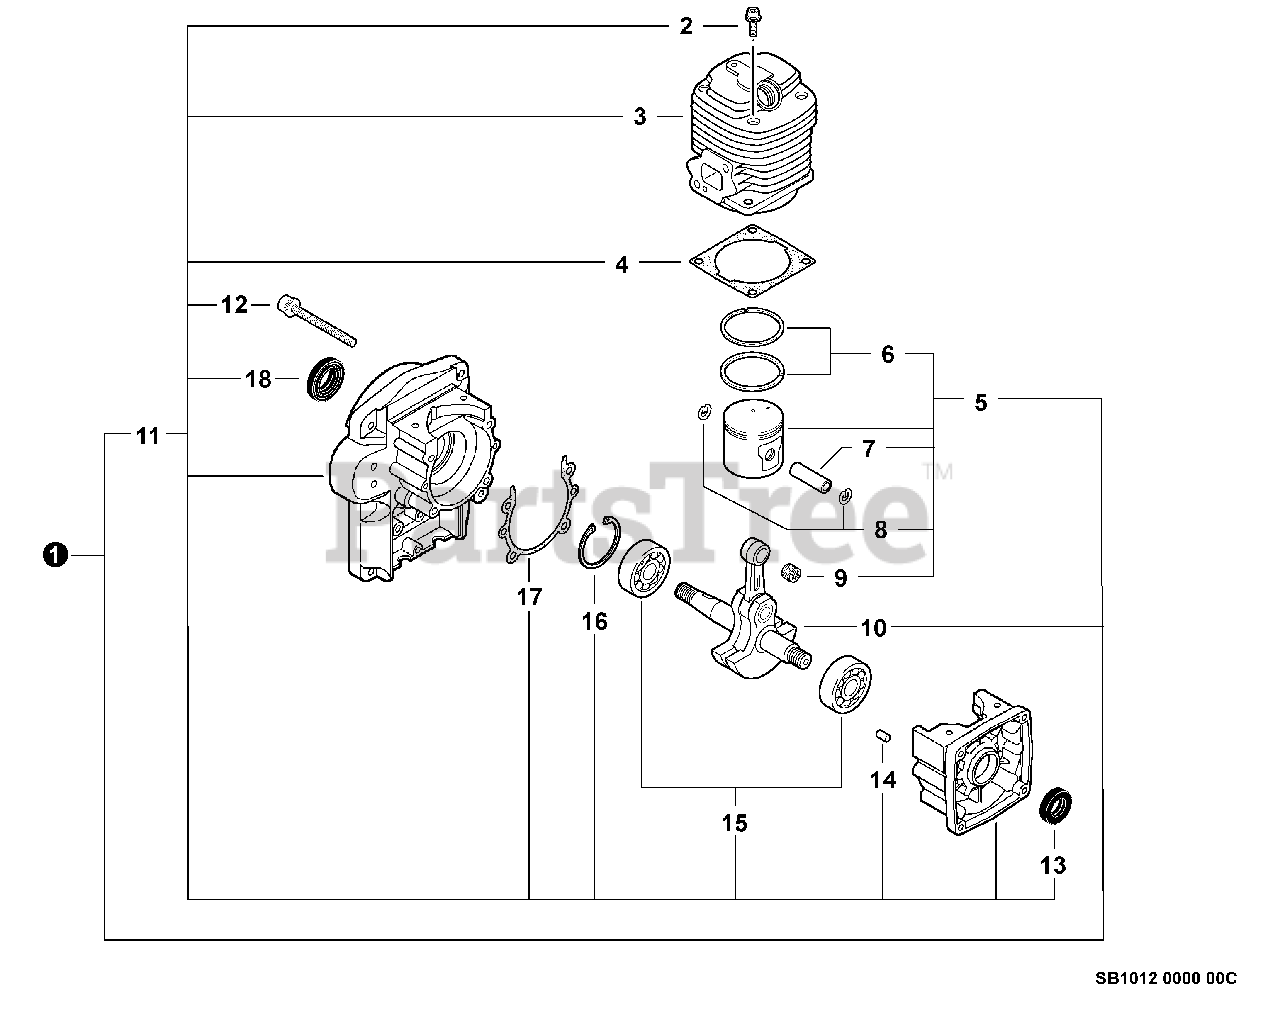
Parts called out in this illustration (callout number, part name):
1	SHORT BLOCK PB-4600
2	BOLT 5×22
3	CYLINDER
4	GASKET, CYLINDER
5	PISTON KIT
6	RING, PISTON
7	PIN, PISTON
8	RING, SNAP 8
9	BEARING, NEEDLE
10	CRANKSHAFT ASSY
11	CRANKCASE KIT
12	SCREW 5×40
13	SEAL, OIL
14	PIN, LOCATING 4
15	BEARING, BALL 6202
16	RING, SNAP 35
17	GASKET, CRANKCASE
18	SEAL, OIL 18
